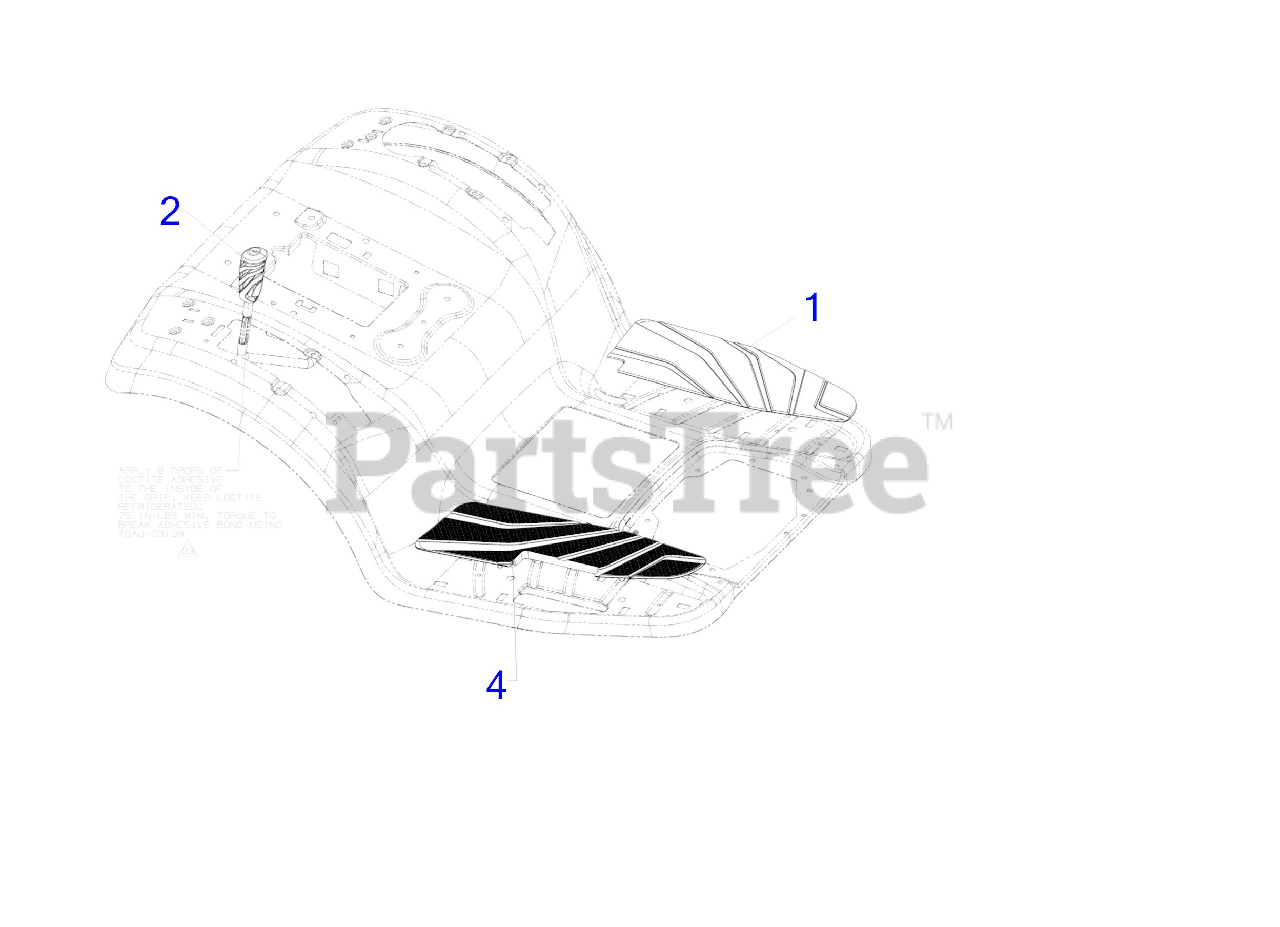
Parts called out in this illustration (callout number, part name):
1	DIFF LOCK FOOTPAD (LH)
2	LIFT HANDLE GRIP .542 ID
4	FOOTPAD (RH)
